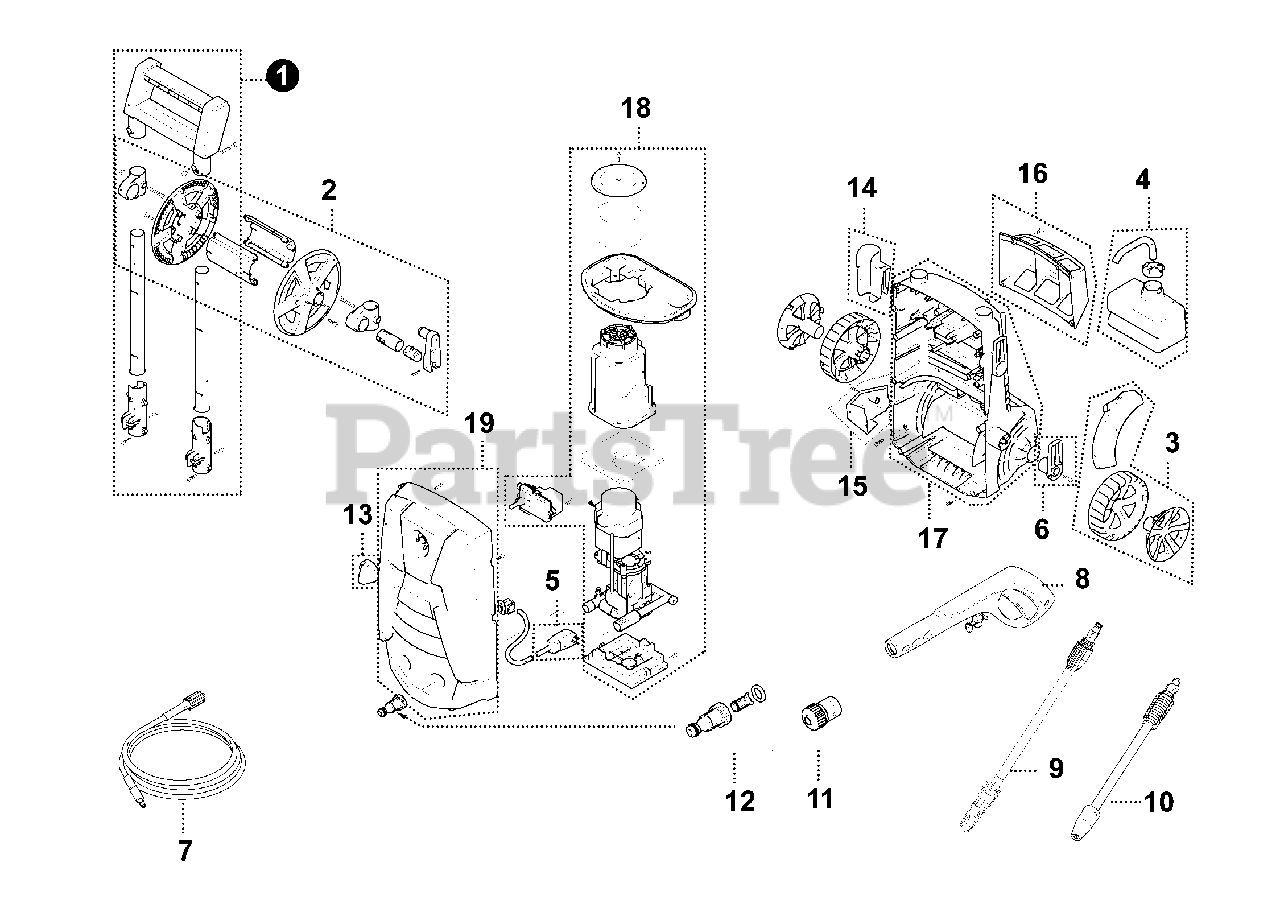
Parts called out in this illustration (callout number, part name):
1	HANDLE ASSEMBLY
2	HOSE REEL ASSEMBLY
3	WHEEL ASSEMBLY W/ GUARD
4	DETERGENT TANK
5	GFCI
6	EXTENSION CORD HOOK
7	HOSE, 20’
8	SPRAY GUN ASSEMBLY
9	HIGH/LOW LANCE/NOZZLE
10	TURBO LANCE/NOZZLE
11	GARDEN HOSE ADAPTER
12	PRESSURE WASHER Q/C FILTER
13	ON/OFF SWITCH
14	LANCE HOLDER
15	NOZZLE TRAY
16	ACCESSORY BRACKET
17	REAR COVER
18	PUMP MOTOR ASSEMBLY
19	FRONT COVER
